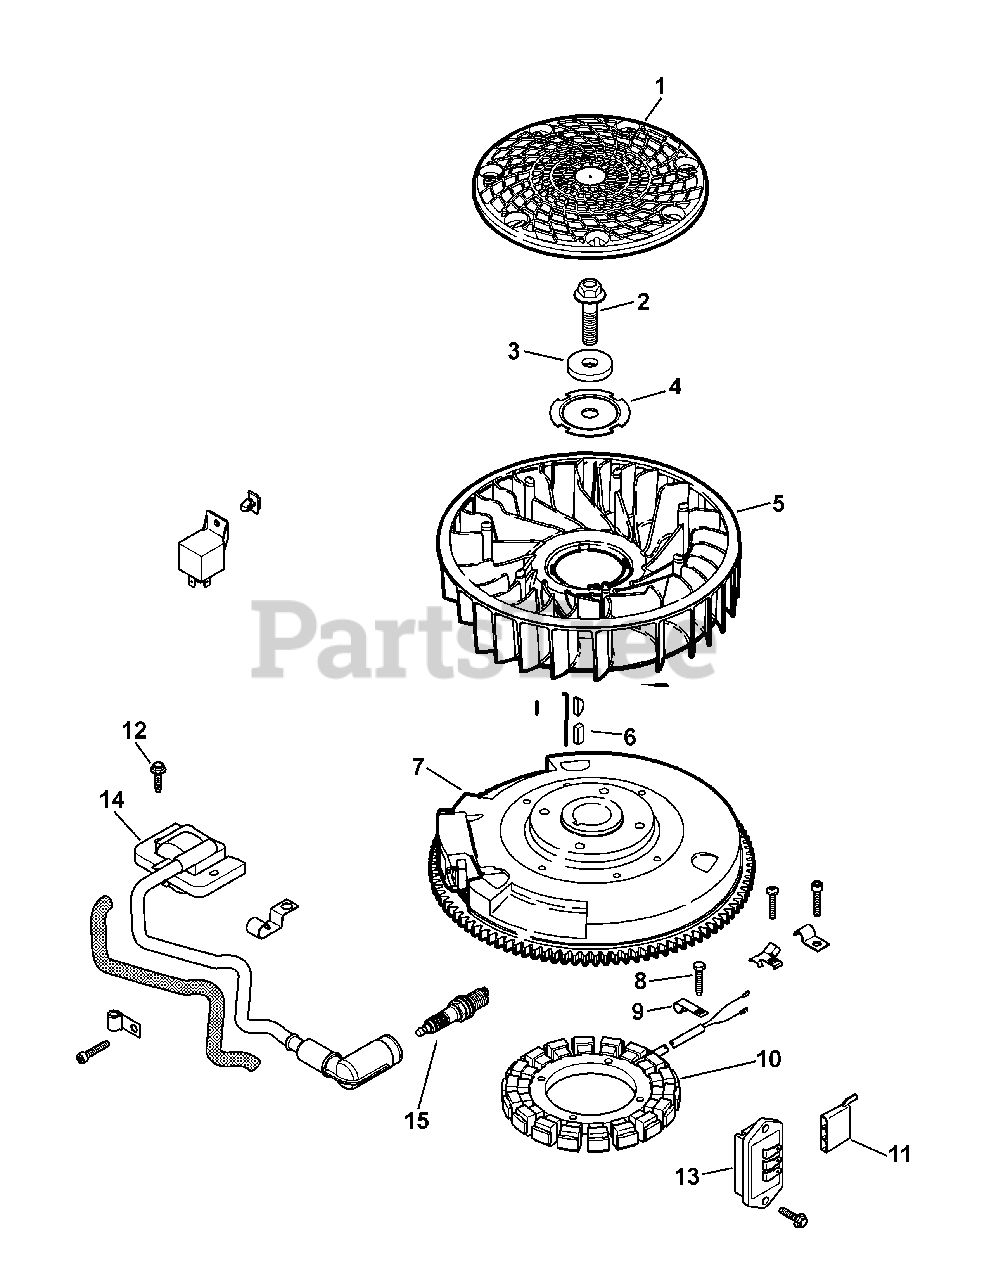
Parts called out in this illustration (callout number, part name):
2	Hex Flange Screw
4	Fan Mounting Plate
6	Straight Flywheel Key
7	Flywheel
8	Thd. Frm. Screw, M5 x 0.8 x 25
10	15 Amp Stator Kit (Inc. KH-25-452-01-S)
12	Flg. Thd. Frm. Screw, M5 x .8 x 20
13	Regulator/Rectifier
14	Ignition Module (CDI Fixed)
15	Spark Plug
